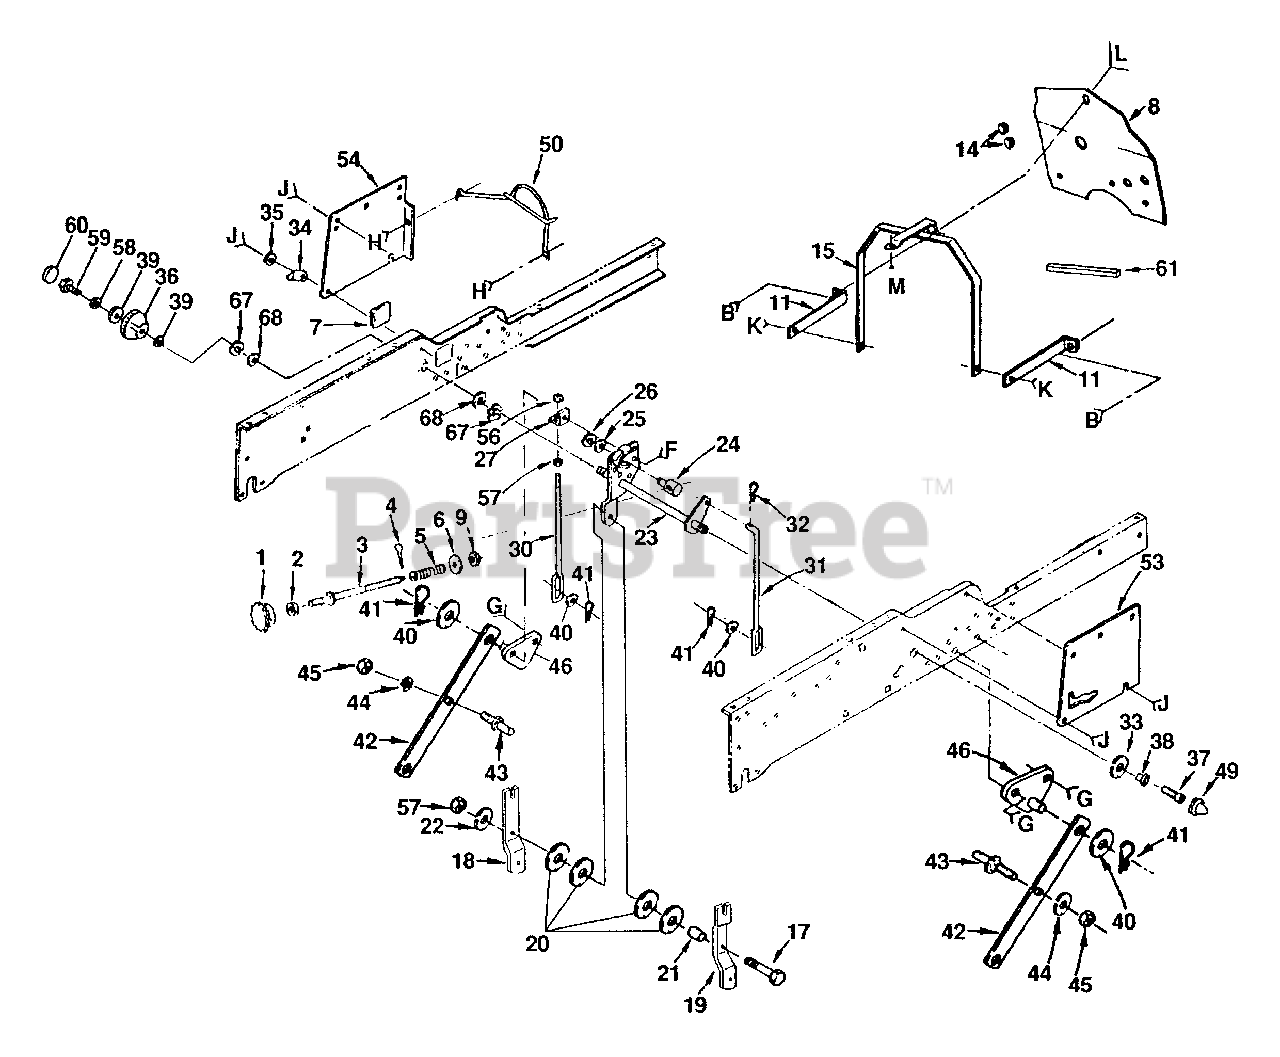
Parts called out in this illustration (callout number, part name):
1	Handle, Adjust, Lift
2	Nut, Hex, Jam 3/8-16
3	Rod, Adjust, Lift
4	Pin, Cotter 3/32 x 3/4
5	Spring
6	Washer 13/32 x 5/8 x 16 Gauge
7	Cover, Access
8	Shield, Head, Read
9	Nut, Special
11	Brace, Head Shield
14	Grommet
15	Support Assembly, Dash
17	Bolt 3/8-16 x 1-3/4
18	Bracket, Lift, L.H.
19	Bracket, Lift, R.H.
20	Washer 17/32 x 1-1/2 x 10 Gauge
22	Washer, Lock 3/8
23	Shaft, Lift
24	Trunnion, Stop Depth
25	Washer 15/32 x 3/4 x 16 Gauge
27	Bracket, Lift LH.
30	Link, Lift, LH.
31	Link, Lift, R.H.
32	Retainer, Spring
33	Washer, Lock Hvy. Hel. Spring
34	Pointer, Height Indicator
35	Washer, Nylon
36	Scale, Height Indicator
37	Bolt, Hex 3/8-16 x 1
38	Hub, Lift Shaft
39	Washer 11/32 x 1-1/2 x 10 Gauge
40	Washer 17/32 x 1 x 16 Gauge
41	Retainer, Spring
42	Arm, Suspension
43	Stud, Pivot, Center
44	Washer, Lock 1/2
45	Nut, Hex 1/2-13
46	Bracket, Suspension, Mower
49	Cap, Spring
50	Guard, Belt, Engine
53	Panel, Side, R.H.
54	Panel, Side, L.H.
56	Locknut 3/8-16
57	Nut, Hex 3/8-16
58	Washer, Lock Hvy. Helical Spring
59	Bolt, Hex Fin 5/16-18 x 1
60	Plug, Hole
61	Strip, Foam
68	Washer 29/32 x 1-1/4 x 16 Gauge
